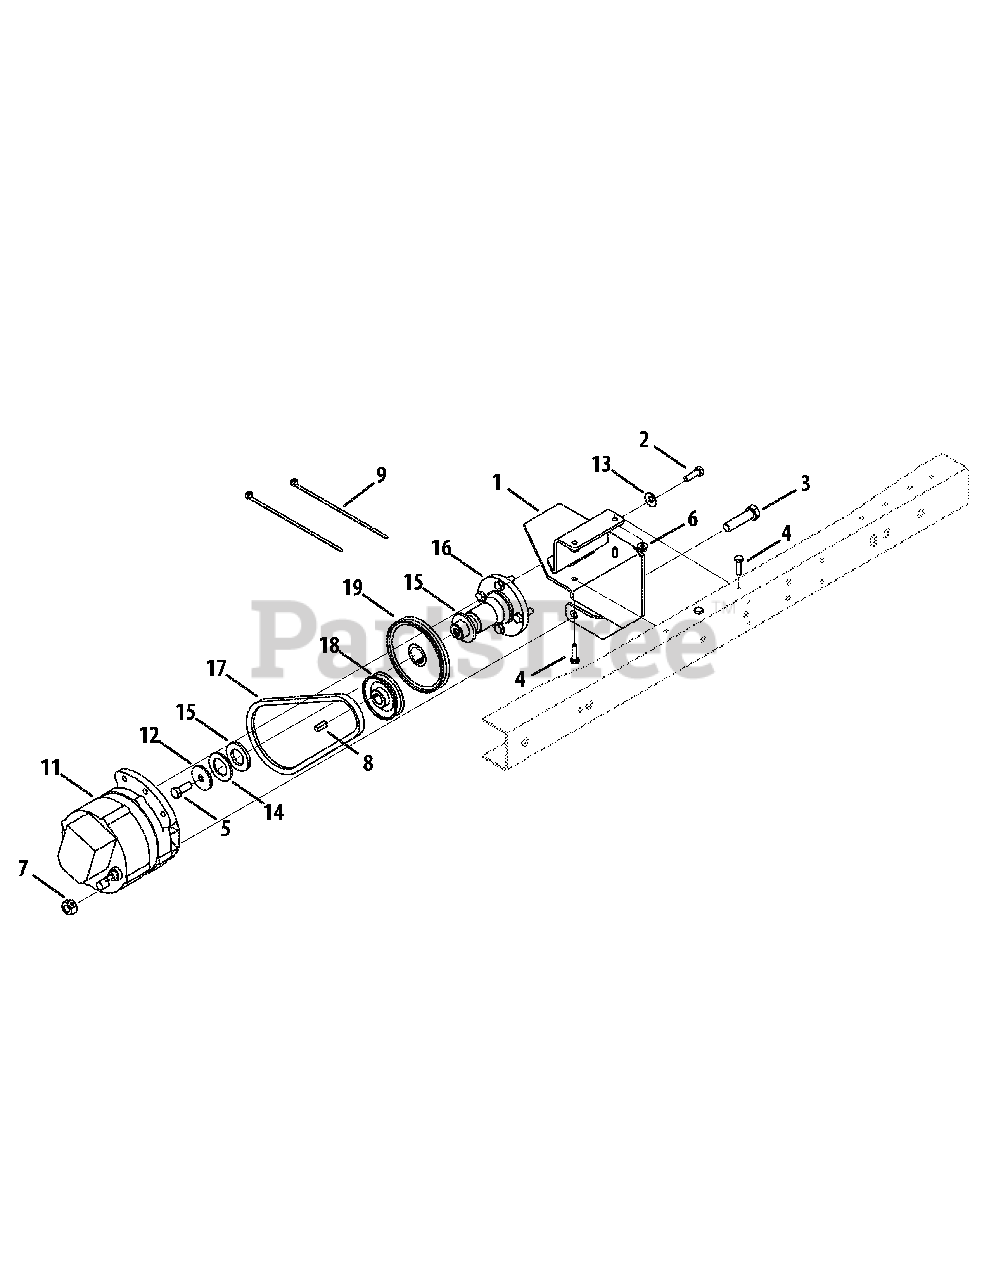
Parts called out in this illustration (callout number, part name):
1	Supprtt., Assy., Altnr., UV, Koh
2	Hhcs, 5/16-18 x 1.00
3	Hhcs, 1/2-13 x 2.00
4	Hhcs, 1/4-20 x 1.00
5	Hhcs, 3/8-16 x 1.00
6	Nut, Flglk., 1/4-20
7	Nut, Hexlk., 1/2-13
8	Sq., Key, 1/4 x .75
9	Tie, Cable
11	Altnr., Aux., 105 Amp
11	Altnr., Aux., 65 Amp
12	Wash., Flat, .390 x 1.5 x .134
13	Wash., Bell, .340 x .872 x .060
14	Wash., Flat, 1.00 x 1.75 x .107
15	Wash., Flat, 1.01 x 1.75 x .172
16	Shft., Kohl., Front, Drive
17	Belt, 3/8 x 24.68
18	Pulley, 2.37 OD, 3L
18	Pulley, 2.65 OD, 3L
19	Pulley, 4.5 OD, 1" Bore
